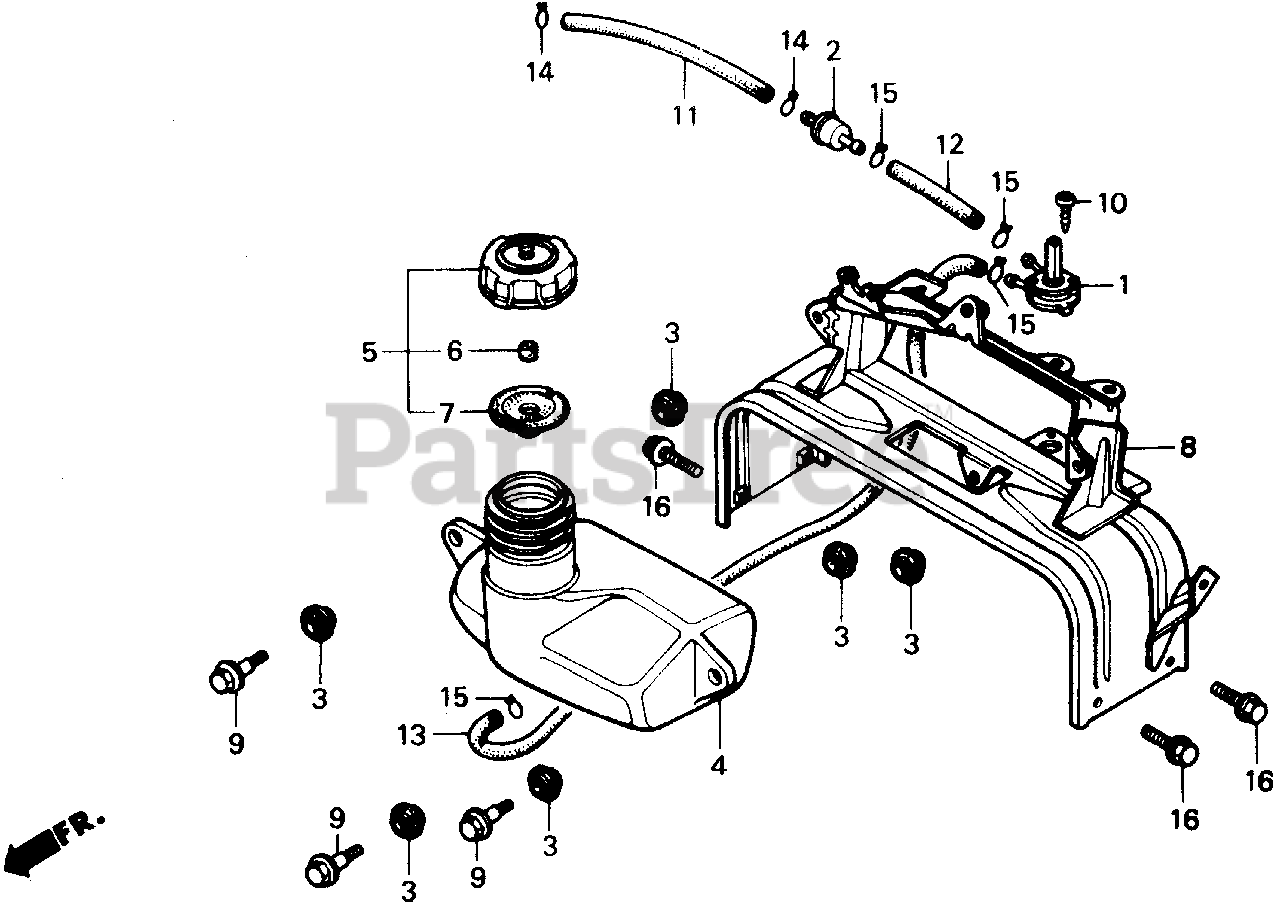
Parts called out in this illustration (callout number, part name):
1	PETCOCK ASSY. (NOT AVAILABLE)
2	FILTER, FUEL
3	RUBBER, TANK SETTING
4	TANK, FUEL (NOT AVAILABLE)
5	CAP, FUEL TANK
5	CAP ASSY., FUEL TANK
6	SPONGE, FUEL CAP BREATHER
7	GASKET, FUEL CAP
8	STAY, FUEL TANK
9	BOLT, TANK SETTING
10	SCREW, TAPPING (3X12)
11	BULK HOSE, FUEL (4.5X3000) (4.5X150)
12	BULK HOSE, FUEL (5.5X3000) (5.5X35)
13	BULK HOSE, FUEL (5.5X3000) (5.5X150)
14	CLIP, TUBE (B8)
15	CLIP, TUBE (B10)
16	BOLT, FLANGE (8X12)
